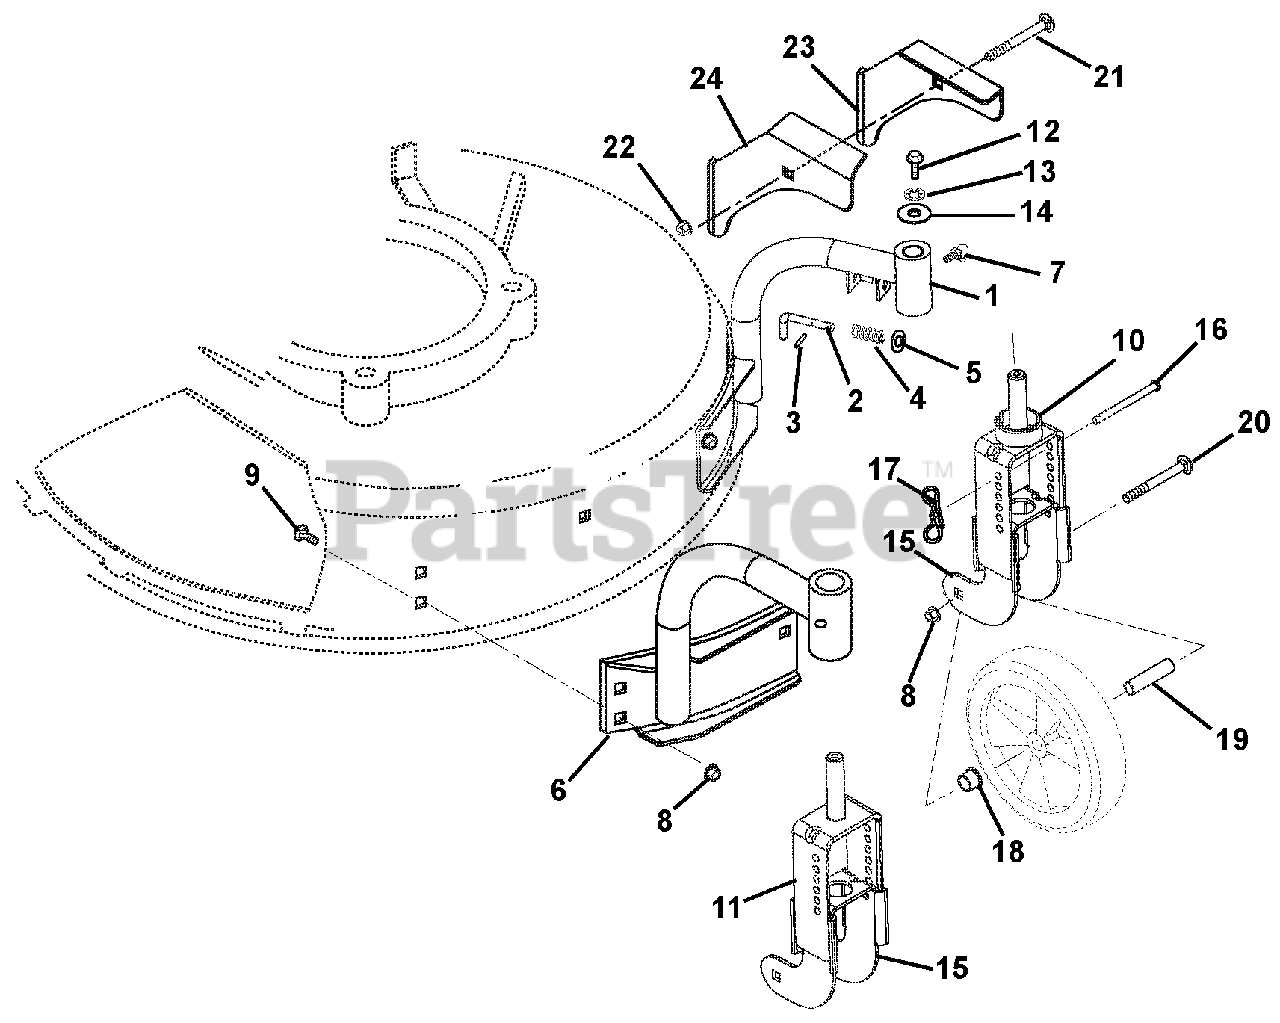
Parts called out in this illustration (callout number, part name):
1	ASSY, MOUNT LH W/BUSHINGS
2	PIN, LOCKOUT
3	PIN-ROLL .093X.50
4	SPRG, COMP--SWVL LOCKOUT
5	@WSHR-FL-STL.281X.62X.065 YWZC
6	ASSY, RH MOUNT W/BUSHINGS
7	FTG-LUBE .25-28X.256 YWZC
8	@NUT-SPNLK-FLG .312-18 YWZC
9	@BLT-RDHDSQNK .31-18X.50 G5YZ
10	YOKE, OUTER LH
11	YOKE, RH OUTER
12	@BLT-HEX .25-20X.75 GR5 YWZC
13	@WSHR-LK .25X.062 REG YWZC
14	WSHR-FL-STL .281X1.000X.063
15	YOKE-INNER
16	PIN, HEIGHT ADJUSTMENT
17	PIN, BOW TIE LOCKING COTTER
18	BSHG-FLG .500X.625X.500X.750
19	SPCR, WHEEL .385X.500X2.00
20	BLT-RDHDSQSHNK.31-18X2.75G2YWZ
21	@BLT-RDHDSQNK .25-20X1.50 G5YZ
22	@NUT-SPNLK-FLG .25-20 YWZC
23	BRACKET, HOOD CABLE--LH
24	BRACKET, HOOD CABLE WELDMENT
